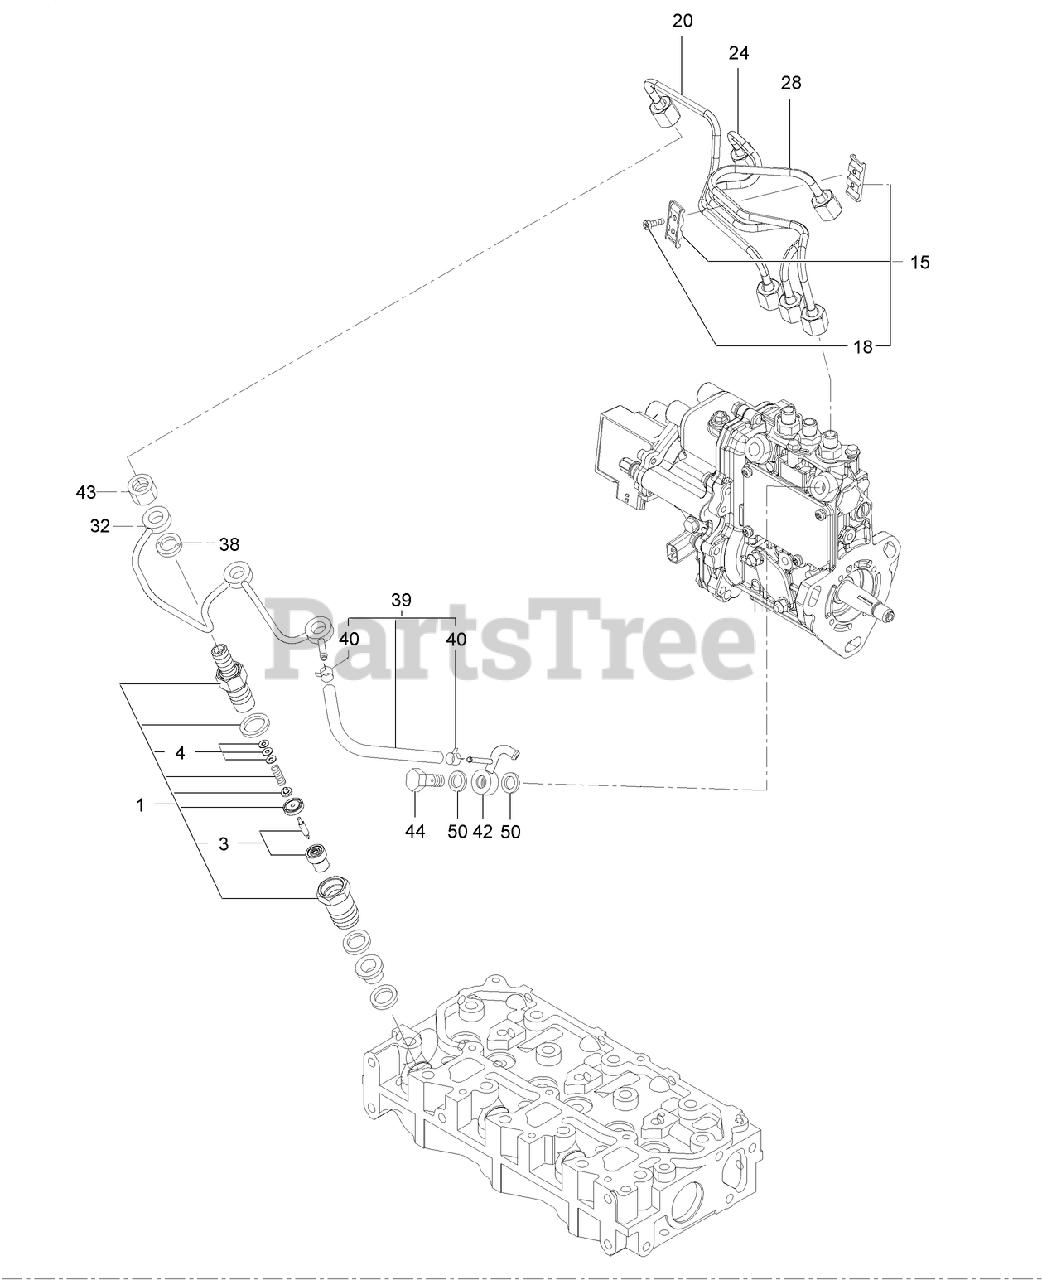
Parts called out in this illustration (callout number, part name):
1	NOZZLE ASM
3	NOZZLE ASM
4	SHIM SET-ADJUSTING
15	RETAINER-PIPE
20	PIPE ASM
24	PIPE ASM
28	PIPE ASM
32	PIPE ASM
38	GASKET
39	HOSE ASM
40	CLAMP-HOSE
42	JOINT-OVER FLOW
43	NUT-NOZZLE
44	VALVE ASM-CHECK
50	WASHER-SEAL
